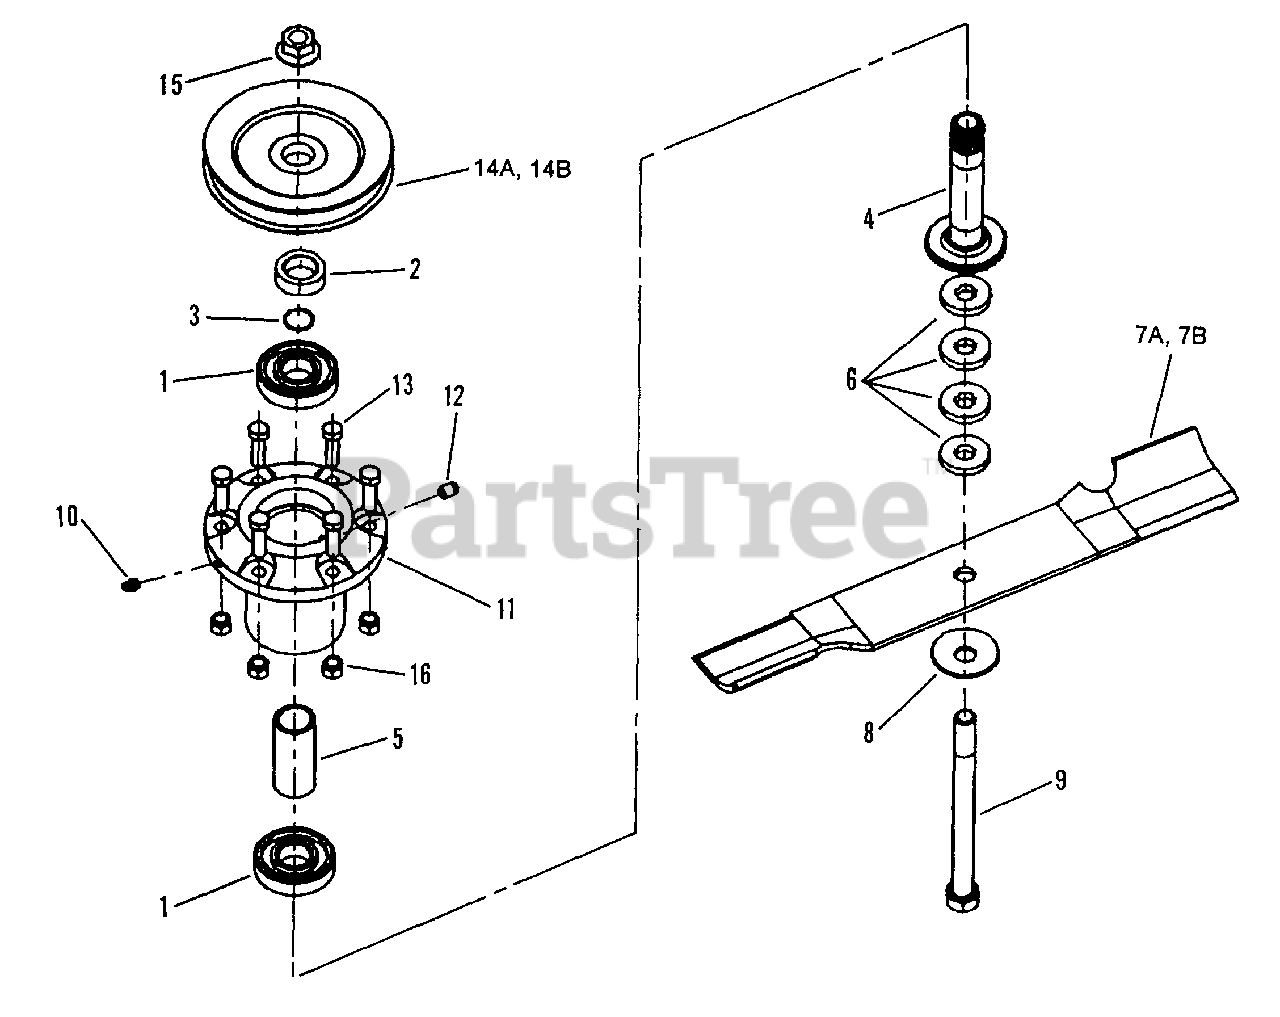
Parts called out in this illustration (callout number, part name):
1	BEARING, Sealed
2	WASHER, Spindle
3	SNAP-RING, Spindle Shaft
4	SHAFT, Spindle
5	SPACER, Bearing
6	SPACER, Blade
7A	BLADE, 18"
7B	BLADE, 16-1/2"
8	WASHER, Beveled
9	BOLT, 5/8-18 x 7-1/2" HEX Head Cap Grade 5
10	LUBE FITTING, 1/4-28 Thread Forming
11	HOUSING, Cutter
12	VENT, Spindle
13	BOLT, 3/8-16 x 1-1/4" Rib Necked
14A	PULLEY, 5-3/4" O.D.
14B	PULLEY, 5-3/4" O.D.
15	NUT, 5/8-18 Hex Flange Lock, Grade 5
16	NUT, 3/8-16 HEX SERRATED FLANGE
